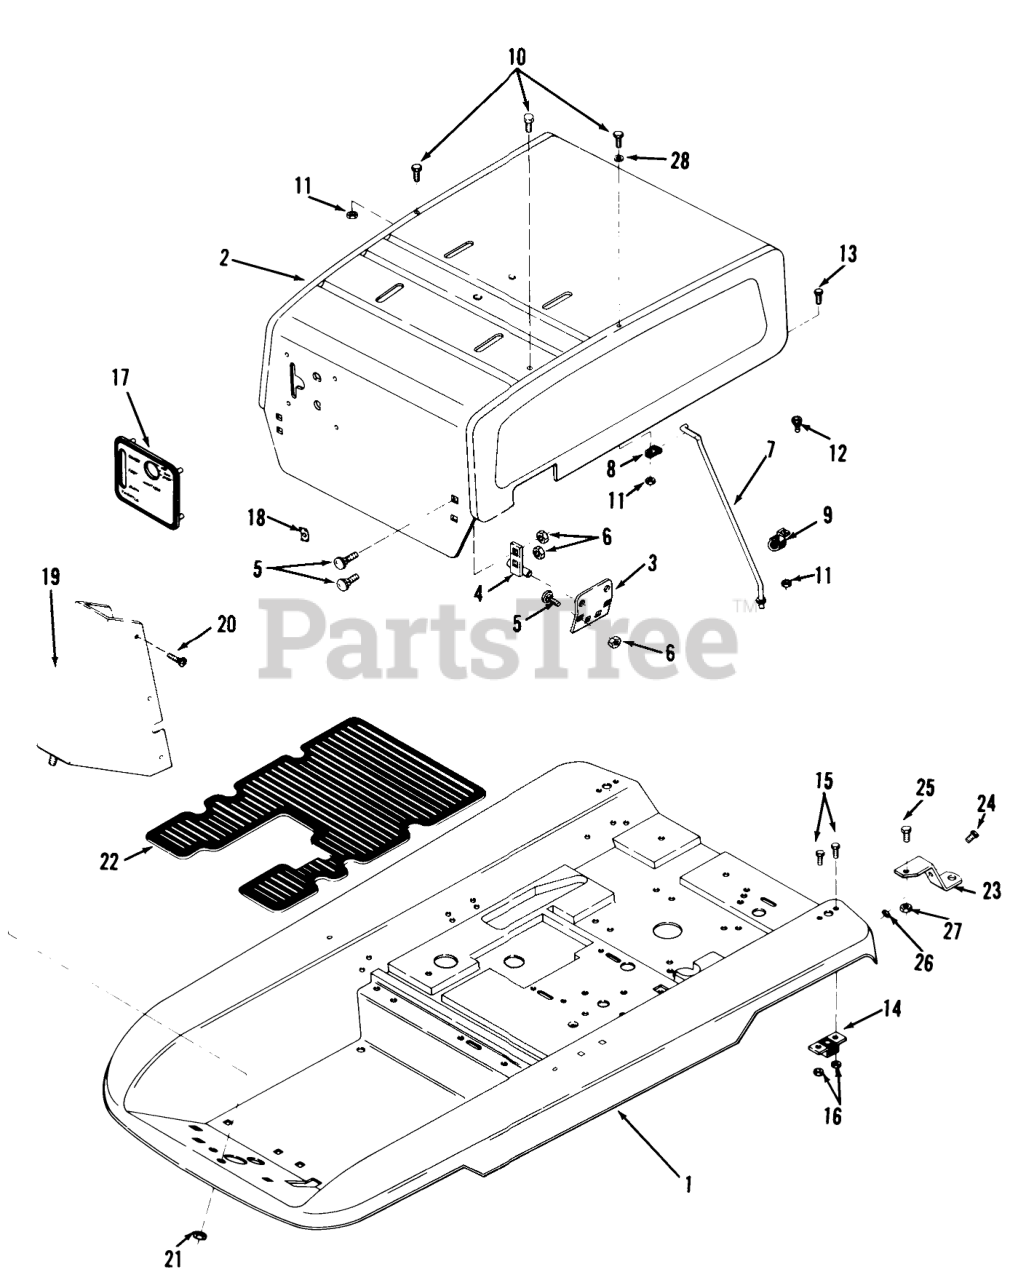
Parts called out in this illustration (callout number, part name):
3	BRACKET R
4	Seat Pivot
5	Bolt
6	Nut
7	ROD-HOOD SUPPORT
10	H H C S
11	Nut
12	Ball Stud
14	Stud Latch
15	Bolt
16	Nut
17	Control Panel
18	SPEED NUT
19	Shroud
20	Screw-Hex HD Slotted
21	Nut
22	FLOOR MAT
23	Hitch Bar
24	Bolt
25	Bolt
26	Nut
27	Nut
